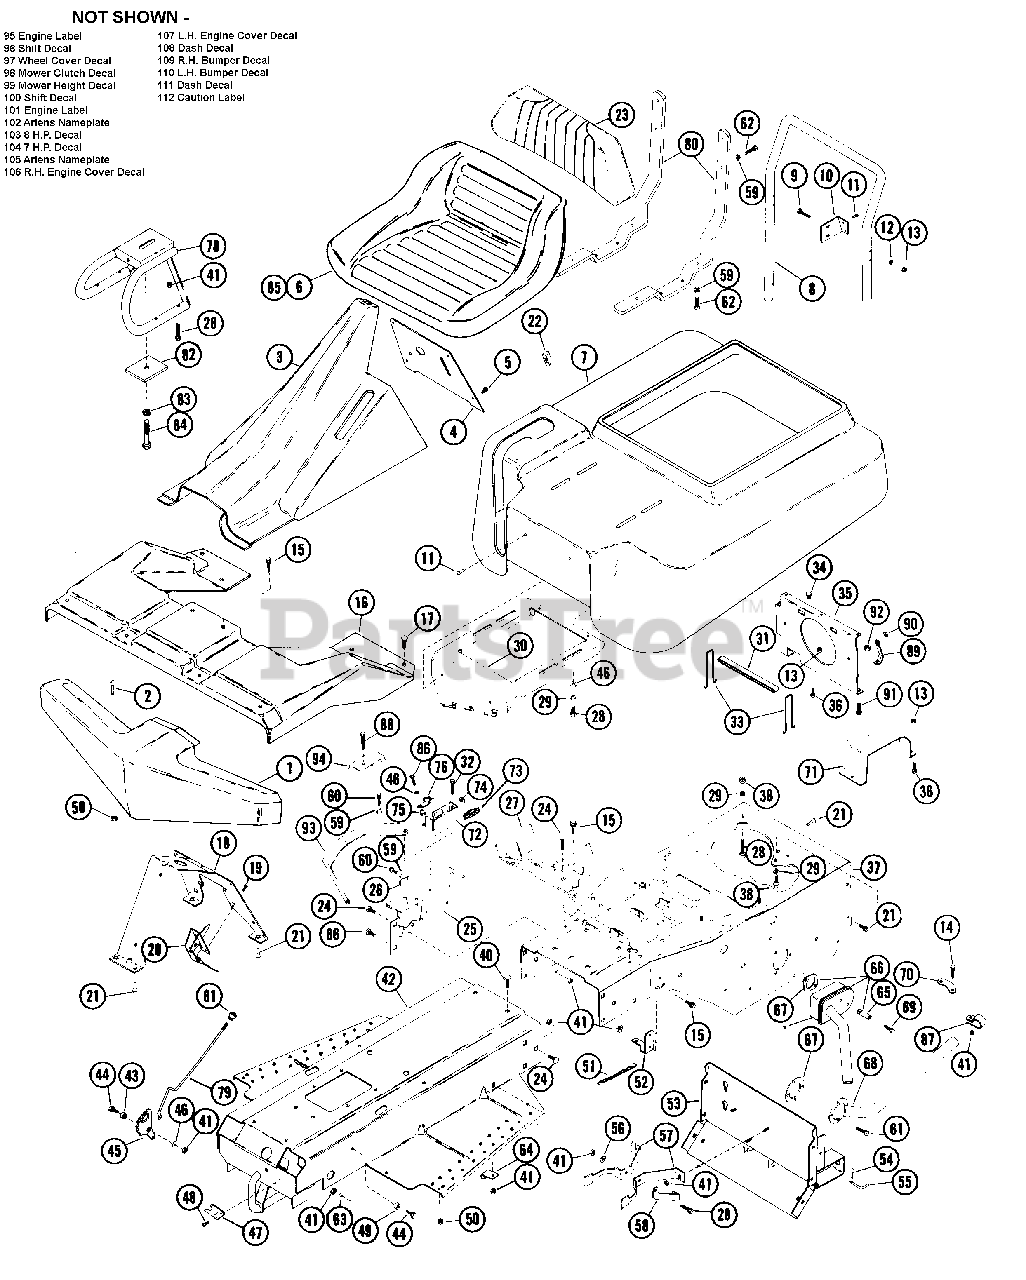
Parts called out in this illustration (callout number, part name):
1	FRONT BUMPER ASSEMBLY
2	SCR-MCH .25-20X.63 CRPH PL
3	HOOD ASSEMBLY
4	DASH COVER
5	SCR-TAP 10-12X.50 CRPH PL A
6	SEAT
7	ENGINE COVER ASSEMBLY
8	SERVICE BAR
9	BLT-HEX .25-20X1.50 PL GR5
10	BRACKET
11	RVT-POP .187X.402 DOME ST
12	WSHR-FL-STL.312X.734X.065PL
13	NUT-LK-CTR .250-20 PL
14	BLT-HEX .31-18X.50 PL GR2
15	BLT-SERHFWH .25-20X.50 PL
16	FRONT WHEEL COVER
17	SCR-SLTR-SERNK .25-20X.62 PL
18	CONTROL PANEL
19	SCR-TAP .50-20X.88 THH
20	THROTTLE CONTROL
21	BLT-SERHFWH .31-18X.50 PL
23	SEAT BACK
24	BLT-RDHDSQSHNK .31-18X.50 YZ
25	SHIFT QUADRANT
27	SEAT HINGE
28	BLT-HEX .31-18X1.50 PL GR2
29	WSHR-LK .312X.097 PL HVY
30	SEAT BRACKET
31	RUBBER BAND
32	SCR-TAP 10-24X.375 CRPH 1A
33	HOOK
34	BUMPER GROMMET
35	SEAT LEG
36	BLT-HEX .25-20X.75 PL GR5
37	REAR FRAME
38	NUT-HEX .312-18
39	BLT-HEX .31-18X1.25 PL GR2
40	BLT-RDHDSQNK .312-18X.62 PL
41	NUT-LK .312-18 GR A PL
42	FRONT FRAME
43	SPACER -SHLD .344X.500X.469
44	BLT-HEX .31-18X1.00 PL GR 2
45	BRAKE LATCH
46	WSHR-FL-STL .38X.875X.083 PL
47	LOCK SPRING
48	SCR-TAP 10-12X.50 CRPH PL A
49	SPACER .344X1.000X.375
50	NUT-LK-FLG .250-20 PL
51	BRAKE CHAIN
52	MOWER BRAKE HOOK
53	REAR COVER
54	PIN-HAIR INT .09X1.88 PL
56	WSHR-FL-STL .323X.625X.062 PL
57	BELT FINGER
58	BELT FINGER BRACE
59	WSHR-LK .250X.077 HVY PL
60	BLT-HEX .25-20X.50 PL GR2
61	SCR-TAP 8-32X.38 SL HWH PL 23
62	BLT-HEX .25-20X.75 PL GR2
63	WSHR-FL-STL .323X.625X.062 PL
65	SPINDLE WASHER
66	MUFFLER REPLACEMENT KIT
67	GASKET
68	EXHAUST PIPE
69	BLT-HEX .31-18X3.00 PL GR5
70	MUFFLER BRACKET
71	HEAT SHIELD
72	SWITCH HOUSING
74	GROMMET, .31 ID
75	BSHG, FLG .325X.499X.26X.88
76	CAM NO SCRAP
77	SHIFT PANEL
78	SEAT BRACKET
79	PARKING BRAKE ROD
80	SEAT BRACE
82	SEAT SUPPORT WASHER
83	WSHR-LK .500X.151 HVY PL
84	BLT-HEX .50-13X1.25 PL GR2
85	SEAT
86	BLT-SERHFWH .31-18X.75 PL
88	PLY-? 8.0X.75
89	CABLE BRACKET
90	GROMMET, .31 ID
91	BLT-HEX .25-20X.63 PL GR2
92	NUT-LK-CTR .375-16 GR A PL
93	SHIFT PANEL
95	ENGINE LABEL
96	SHIFT DECAL
100	SHIFT DECAL
101	ENGINE LABEL
103	8 H P ENGINE DECAL
104	7 HP ENGINE DECAL
106	R H ENGINE COVER DECAL
107	L H ENGINE COVER DECAL
108	DASH DECAL
111	DASH DECAL
